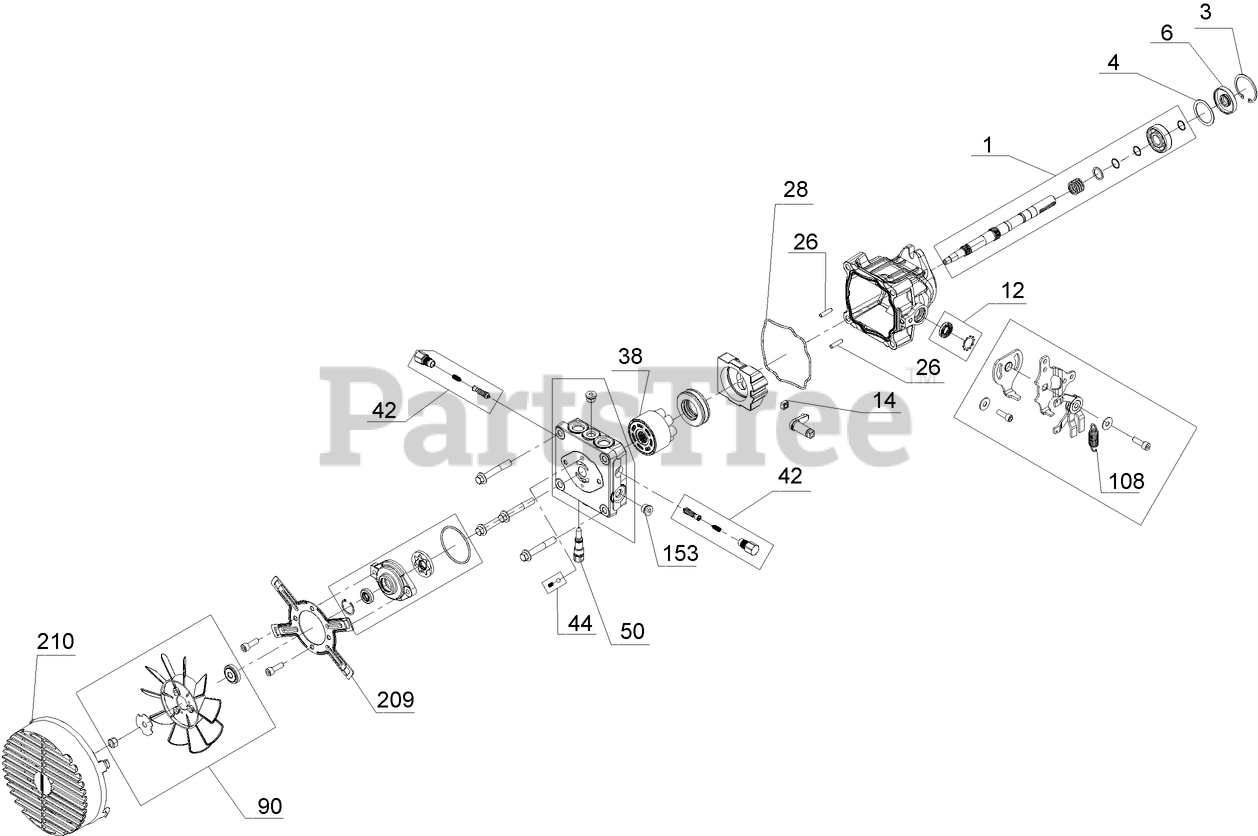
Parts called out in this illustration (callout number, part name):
1	KIT-INPUT SHAFT AND BEARING
3	Ring-Retaining
4	Washer-Flat
6	SEAL-LIP
12	Trunnion Seal Kit
14	Guide-Slot
26	Pin-Headless, Straight
38	Cylinder Block Kit
42	KIT-SHOCK VALVE
44	CHARGE RELIEF VALVE KIT
50	BYPASS VALVE KIT
90	FAN HUB KIT
108	SPRING-EXTENSION
153	PLUG-THREAD, STRAIGHT
209	Bracket-Fan
210	GUARD-FAN, PUMP
